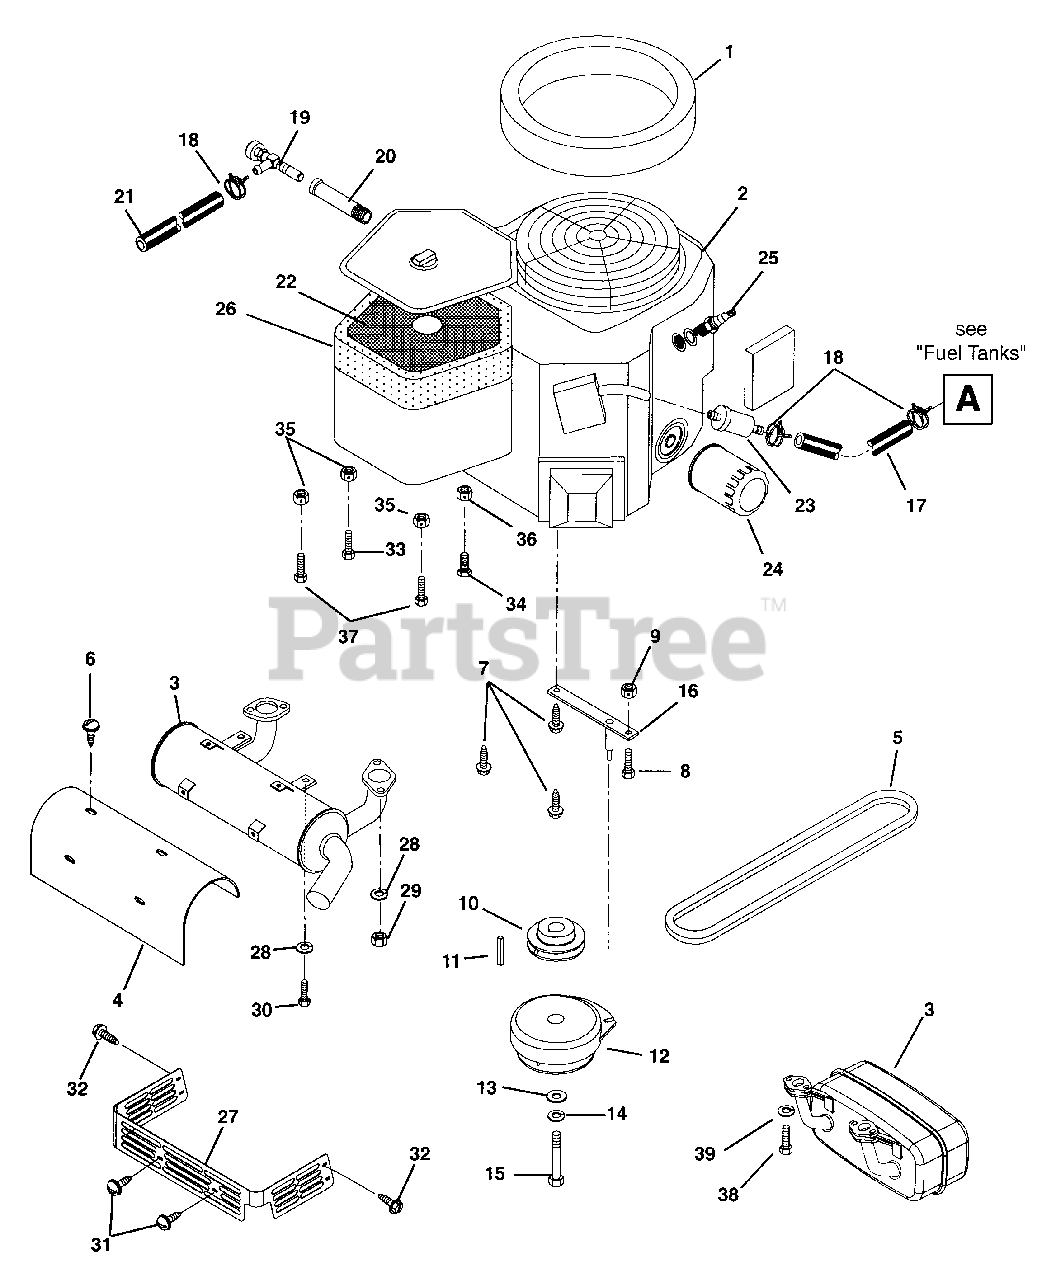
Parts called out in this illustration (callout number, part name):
1	Seal-Kohler to Adapter
1	Seal-Foam Robin to Plenum
2	25HP-Kohler Command Vertical
2	Engine-Robin EH6.5V
2	Engine-Briggs & Stratton Vanguard 20HP
3	Muffler-Kohler CV18-CV25
3	Muffler
4	Heat Shield CV18-25
5	V-Belt HA-Section 73.50 x .531
6	Screw-Tapping w/Washer
7	Screw-Tapping Hex-Washer-Head .38-16 x 1.00
8	Bolt-Hex .31-18 x 1.75 Grade 5
9	Nut-Locking-Center .31-18
10	Pulley-4.46 DIA x 1.12 Bore
11	Key-Square .25 x 1.00 x .25
12	Electric Clutch
13	Washer-Flat-Steel .515 x 1.625 x .250
14	Washer-Locking .44 x .109
15	Bolt-Hex .44-20 x 3.00 Grade 5
16	Anchor-Clutch
17	Gas Line-Bulk 1/4" ID
18	Hose-Clamp
19	Cock-Oil Drain
20	Adapter-Oil Drain
21	Gas Line-Bulk 1/4" ID
22	Air Filter
23	Fuel Filter
24	Oil Filter
25	Spark Plug
26	Element, Precleaner
27	Heat Shield-Robin 22
28	Washer-Lock .31 x .078 Regular
29	Nut-Hex M8-1.25
30	Bolt-Hex M8-1.25 x 20
31	Screw-Tapping With Washer
32	Screw-Tapping.25-20 x .50
33	Bolt-Hex .38-16 x 1.75 Grade 5
34	Bolt-Hex .31-18 x 1.75 Grade 5
35	Nut-Locking-Nylon .38-16
36	Nut-Locking-Nylon .312-18
37	Bolt-Hex .38-16 x 1.50
38	Screw-Cap .31-18 x .75
39	Washer-Lock .31 x .078
